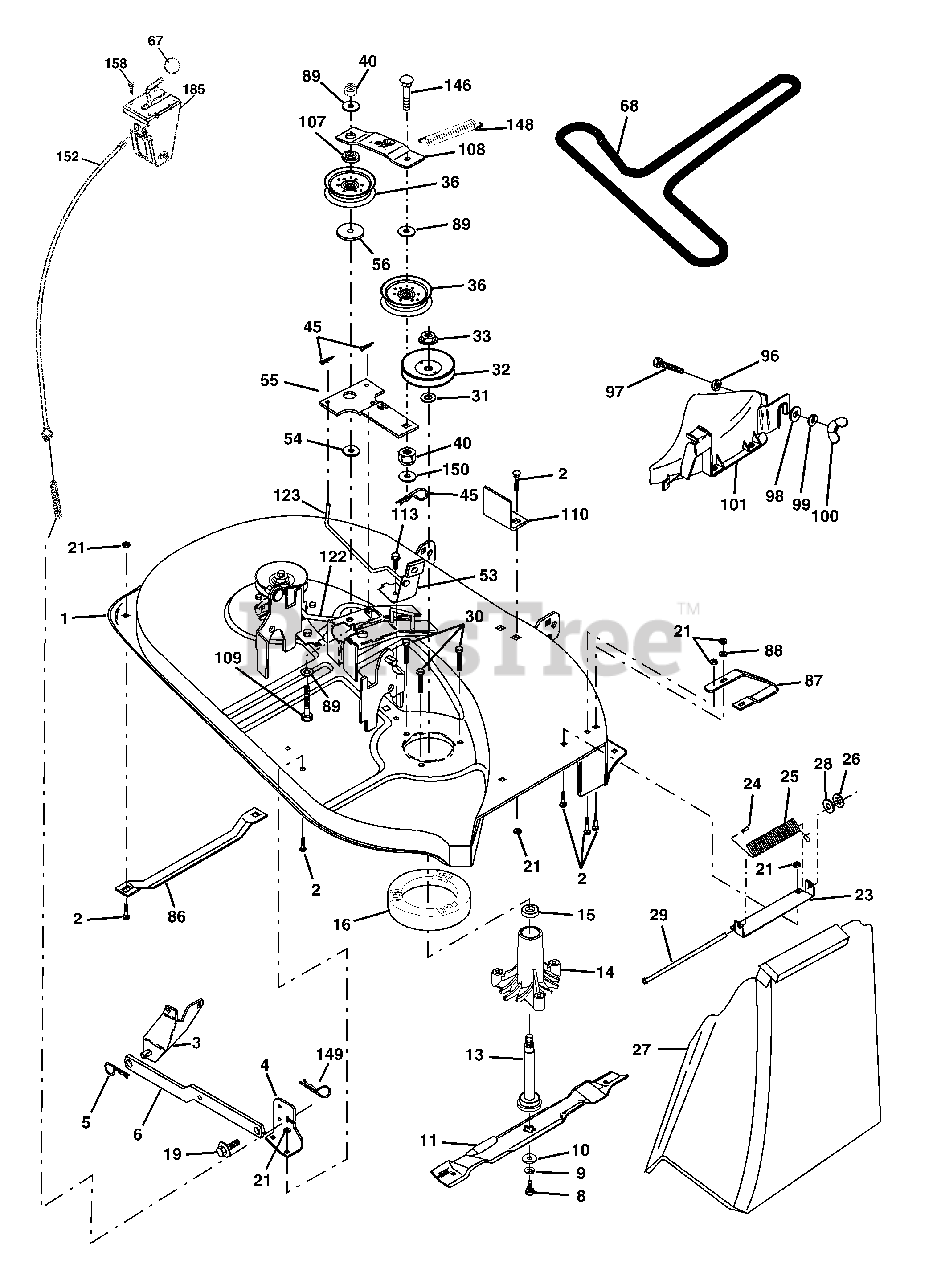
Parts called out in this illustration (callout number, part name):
1	Mower Housing Assembly
2	Bolt Carriage 5/16-18 x 3/4
3	Bracket Asm Fr. Sway Bar
4	Bracket Deck Sway Bar 38"/42"
5	Retainer Spring
6	Bar Sway Deck
8	Bolt 3/8-24 x 1.25 Gr. 8
9	Washer, Lock 3/8
10	Washer, Hardened
11	Blade Mower
13	Shaft Assembly, Mandrel, Vented
14	Housing, Mandrel, Vented
15	Bearing, Ball, Mandrel
16	Stripper, Vented Mower Deck
19	Bolt, Shoulder
21	Nut
23	Bracket, Mower Deflector
24	Cap, Sleeve
25	Spring, Torsion, Deflector
26	Nut, Push
27	Shield, Deflector
28	Washer 11/32 x 5/8 x 16 Ga.
29	Rod, Hinge
30	Screw Thdrol.
31	Washer, Spacer
32	Pulley, Mandrel
33	Nut, Toplock
36	Pulley, Idler, Flat
40	Nut, Crownlock 3/8-16 unc
45	Retainer
53	Brake Assembly
54	Washer, Hardened
55	Idler Arm Assembly
56	Spacer, Retainer
67	Knob
68	V-Belt, 42" Mower
86	Runner, LH
87	Runner, RH
88	Washer 11/32 x 3/4 x 16 Ga.
89	Washer 13/32 x 13/16 x 11 Ga.
96	Bolt 3/8-16 x 1-1/4 Mulcher
97	Nut Centerlock 3/8-16 unc
107	Spacer Retainer
108	Stiffener, Idler Arm
109	Bolt, Hex Hd 3/8-16 x 2-1/2
110	Upstop Deck Front 38"
113	Screw 5/16-1/ x 3/4
122	Rod, Brake LH
123	Rod, Brake RH
146	Bolt Carriage Idler
148	Spring Return Idler
149	Retainer Spring Yellow
150	Washer 9/32 x 3/4 x 16 Ga.
152	Clutch Cable 38"/46"
158	Screw Hex Thd Cut 1/4-20 x 1/2
185	Head Asm Cable Clutch
